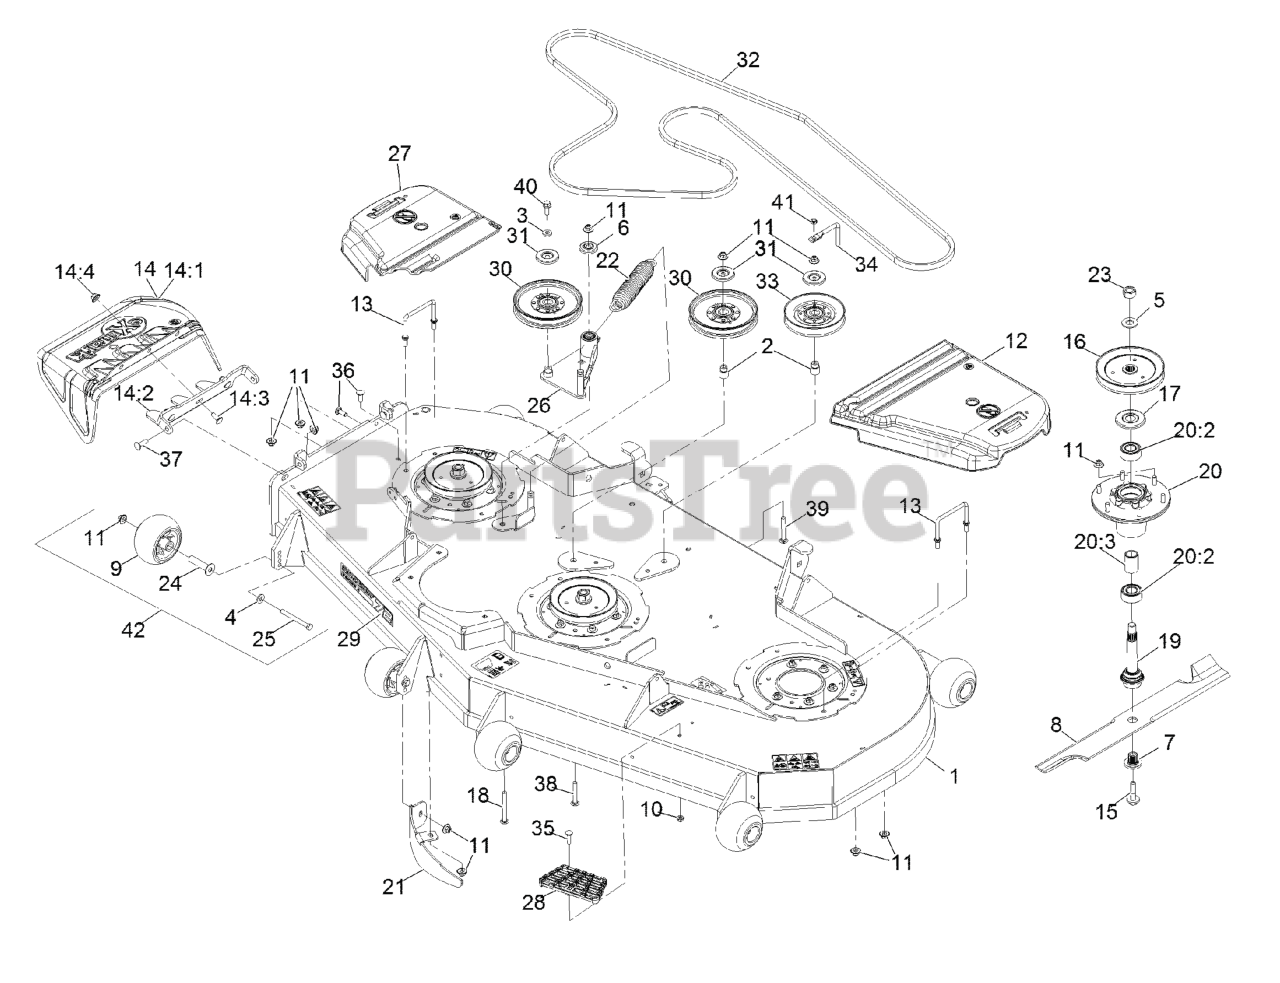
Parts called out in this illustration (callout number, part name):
1	Deck-724
2	BUSHING-IDLER
4	WASHER-BELLEVILLE
6	GUARD-TOP
7	BUSHING,SPLINED
9	ROLLER-SCALP, ANTI
10	NUT-HF, NI
11	Nut-Nyloc 3/8-16 Flg
12	COVER-BELT, LH
13	WIREFORM-COVER
14	ASM,DISCHARGE CHUTE
14:1	CHUTE,DISCHARGE
14:2	BRACKET,DISCHARGE CHUTE
14:3	SCREW-CARR
14:4	Nut-Nyloc 3/8-16 Flg
15	SCREW,SEMS 1/2-20 X 2.19
16	SHEAVE,BLADE DRIVE 6.50
17	GUARD-BEARING, TOP
18	BOLT-SHOULDER, CARRIAGE 3/8-16 X 3 1/2
19	ASM-SPINDLE AND SEAL
20	ASM-Cutter Hsg
20:2	Bearing-3205 Trashguard
20:3	Spacer-Bearing
21	BAFFLE-DOGLEG, LZ72
22	SPRING-EXTENSION
23	NUT-HEX
24	AXLE, ROLLER
25	SCREW-HH 3/8-16 X 3 3/4 GR 8
26	IDLER ARM ASM
27	SHIELD-BELT
28	STEP-DECK
29	DECAL, 724
30	IDLER-PULLEY
31	SHIELD-DUST
33	IDLER V
34	GUIDE-BELT
35	Bolt-Carriage 5/16-18 X 1 1/4
36	SCREW-CARR
37	Bolt-Carriage 3/8-16 X 1 1/4
38	SCREW-CARR
39	SCREW-CARR
40	SCREW-HHF
42	KIT, ANTI-SCALP ROLLER
